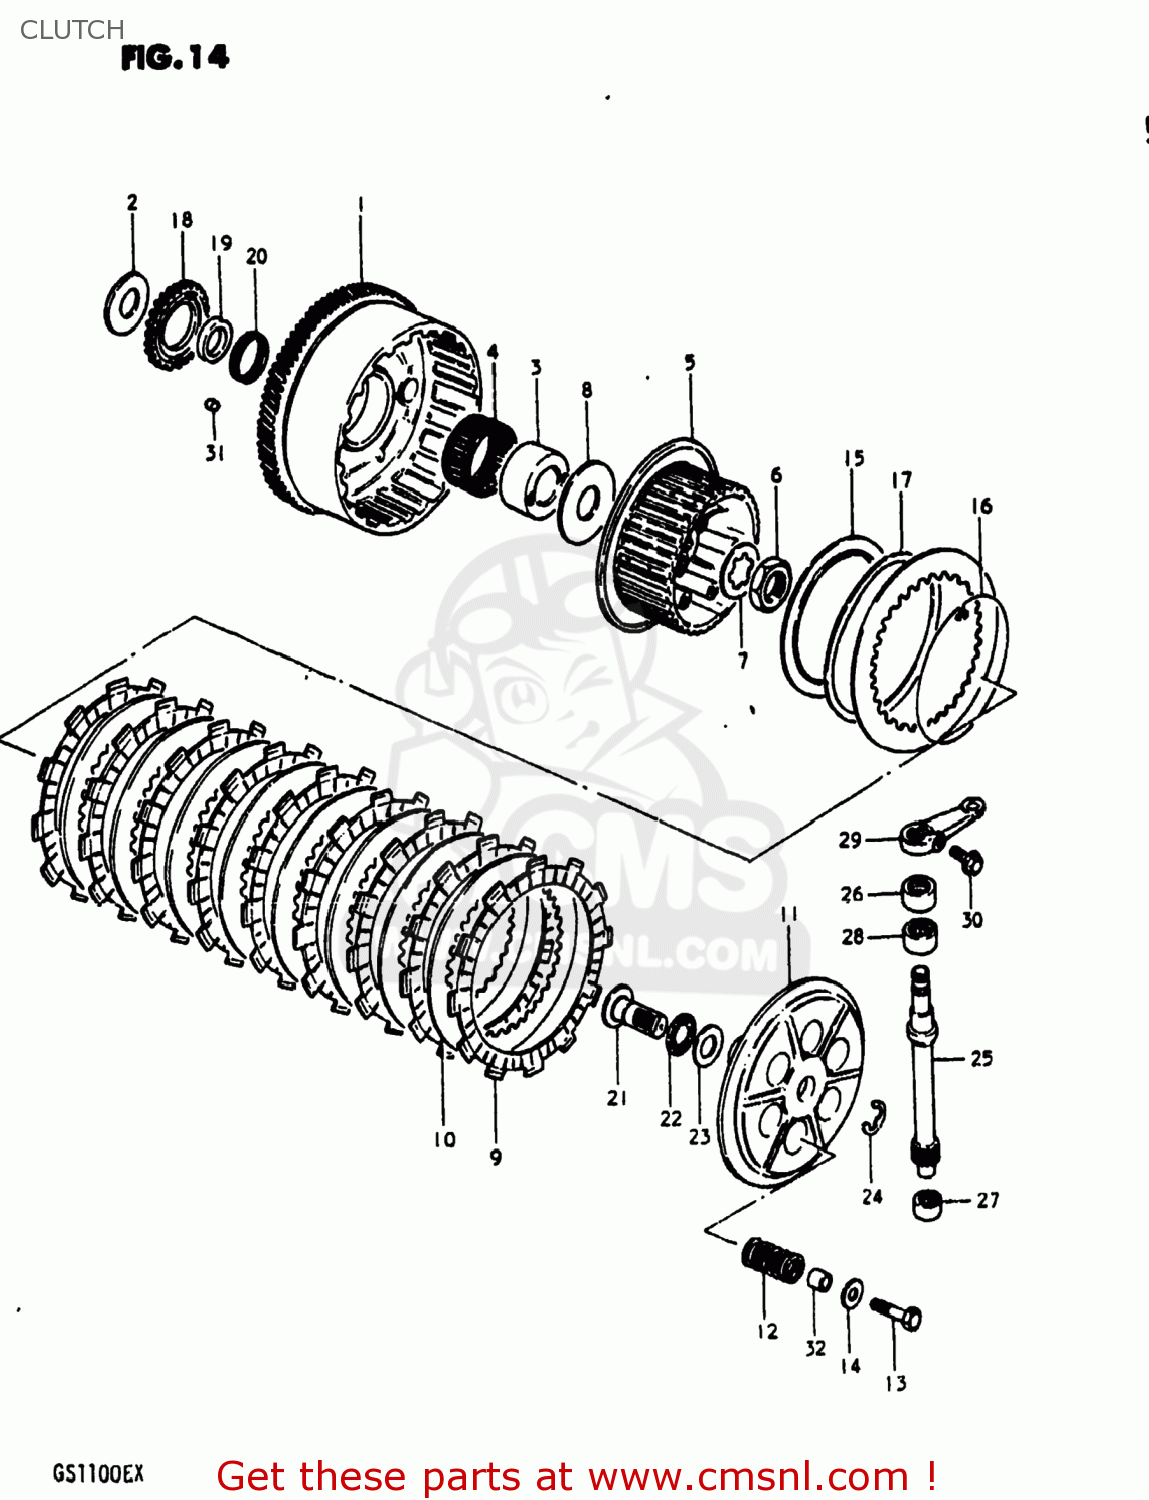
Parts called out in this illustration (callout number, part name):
1	GEAR ASSEMBLY,PRIMARY DRIVE
2	WASHER
3	SPACER
4	BEARING
5	HUB,CLUTCH SLEEVE
6	NUT
7	WASHER,LOCK
8	WASHER(25X66X3.5)
9	PLATE,CLUTCH DRIVE (MCA)
10	PLATE,CLUTCH DRIVEN (NAS)
11	DISC,CLUTCH PRESSURE
12	SPRING
13	BOLT
14	WASHER
15	SEAT,WAVE WASHER
16	RING,STOPPER
17	WASHER
18	GEAR,OIL PUMP DRIVE
19	SPACER,OIL PUMP DRIVE GEAR
20	BEARING(36X40X10)
21	RACK,CLUTCH RELEASE
22	BEARING(15X28X2)
23	WASHER
24	E RING 12MM
25	PINION,CLUTCH RELEASE
26	OIL SEAL
27	BEARING(12X19X12)
28	BEARING(15X22X12)
29	ARM,CLUTCH RELEASE
30	BOLT 6X20
31	CUSHION,PRIMARY DRIVEN GEAR
32	SPACER
